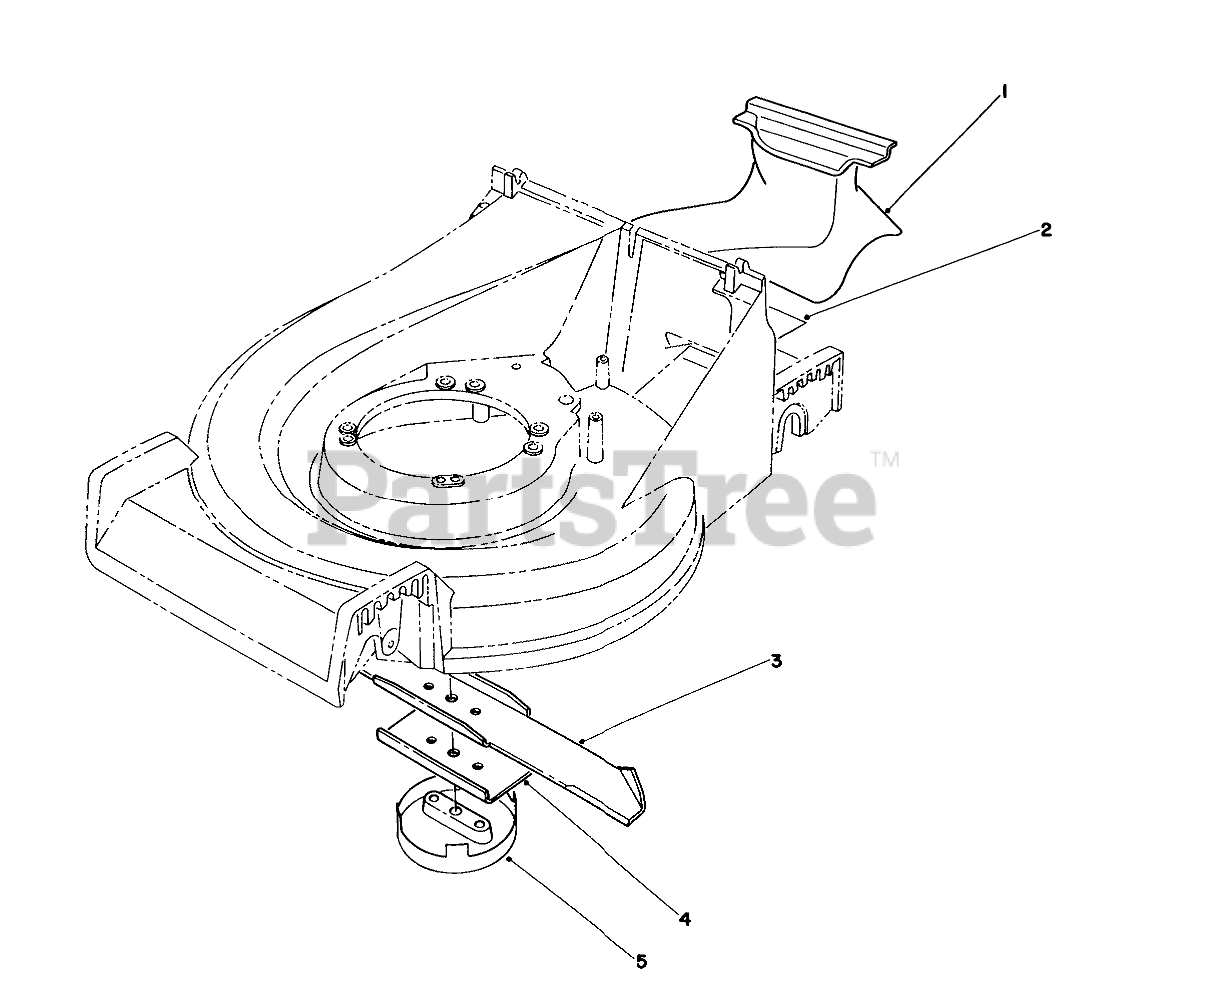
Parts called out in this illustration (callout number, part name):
1	RECYCLER PLUG
2	DECAL - MULCHER KIT
3	BLADE-21in
4	Stiffener
5	CUP-SCALP, ANTI
